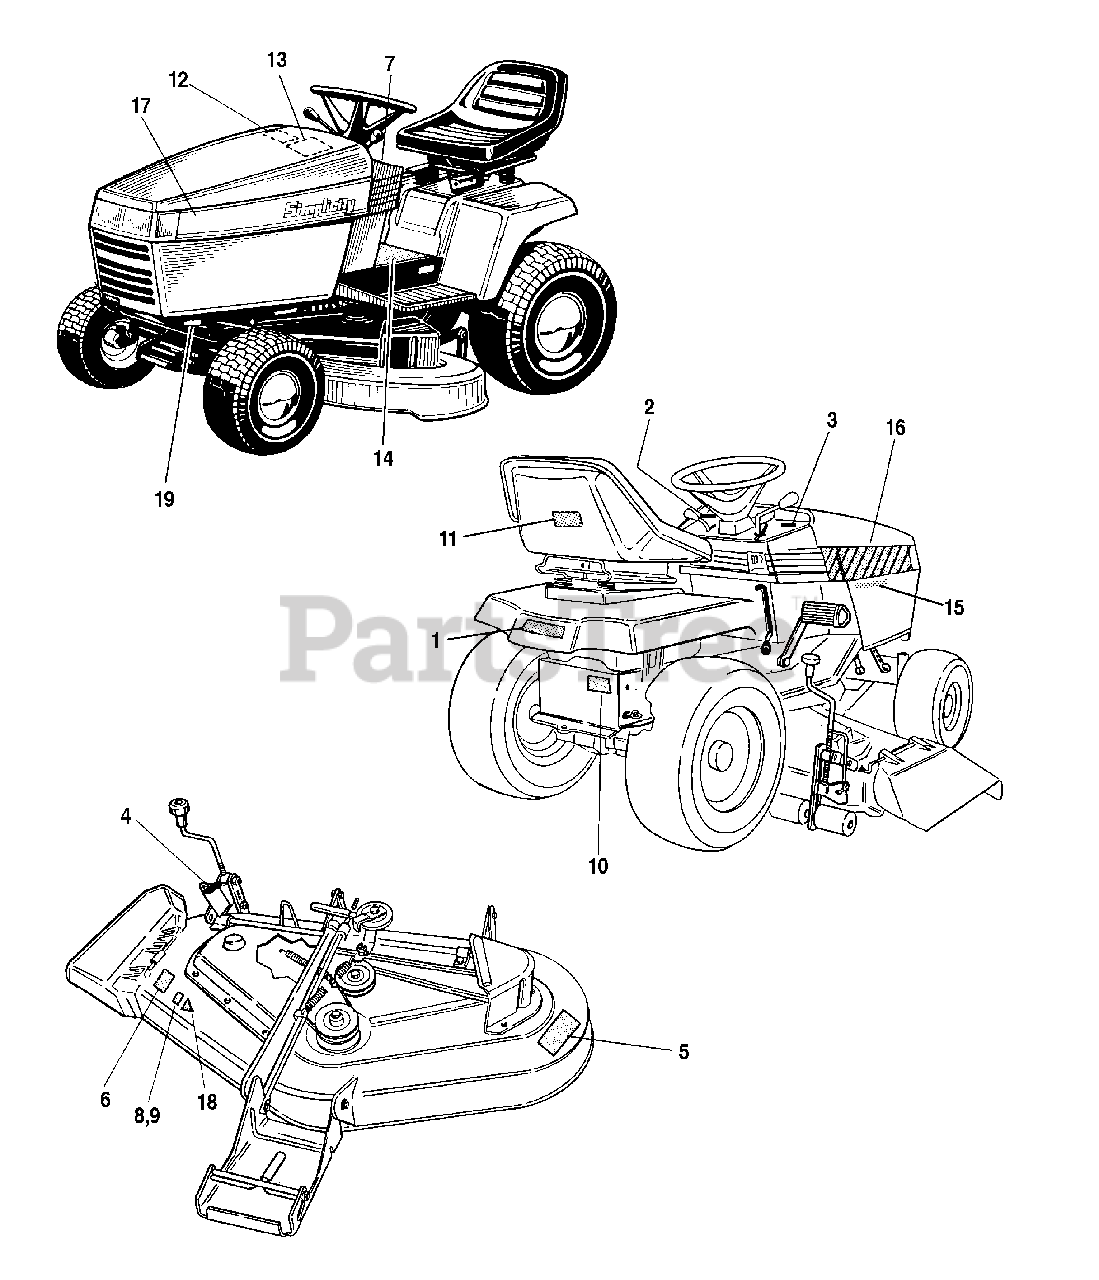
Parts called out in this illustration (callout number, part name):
1	DECAL, Simplicity Logo
2	DECAL, Indicator, L. H. Dash
3	DECAL, Indicator, R. H. Dash
4	DECAL, Mower Height
5	DECAL, Danger (Hand under deck)
6	DECAL, Danger (Chute in place)
7	DECAL, Choke (Dash)
8	DECAL, Cutting Width, 38"
9	DECAL, Cutting Width, 44"
10	DECAL, Release Valve
11	DECAL, USA Logo
12	DECAL, Paint
13	DECAL, Belt, Blade
14	DECAL, Operating Instructions
15	DECAL, Model, 14 V-Hydro
15	DECAL, Model, 14 Hydro
15	DECAL, Model, 16 Hydro
15	DECAL, Model, 15 Gear
15	DECAL, Model, 15 Hydro
16	DECAL, Hood, RH
17	DECAL, Hood, LH
18	DECAL, OPEI
19	I.D. PLATE
